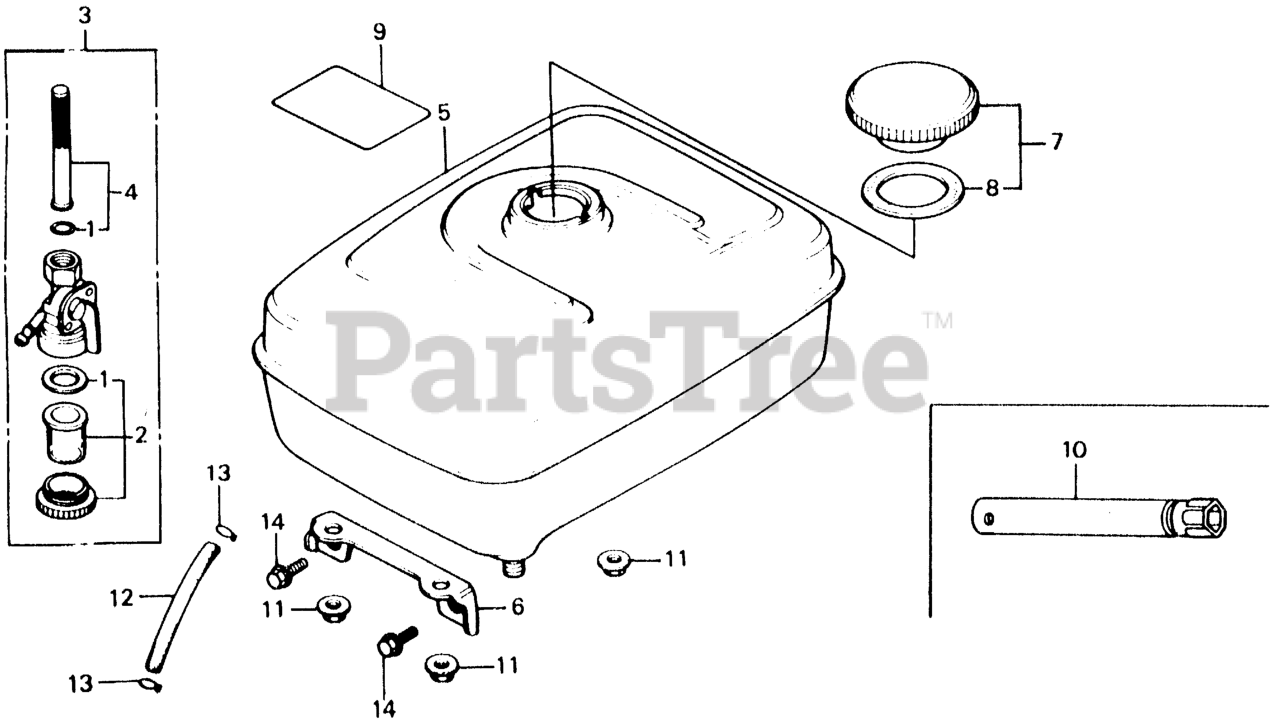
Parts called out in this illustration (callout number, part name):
1	GASKET SET, PETCOCK (CONTAINS 1 LARGE & 1 SMALL. USE AS NEEDED)
2	CUP, FUEL STRAINER
3	PETCOCK ASSY.
4	SCREEN SET
5	TANK, FUEL *NH31R* (MCKINLEY WHITE)
6	STAY, FUEL TANK
7	CAP, FUEL FILLER (BLACK) Use up to Engine SN 2115700.
7	CAP, FUEL FILLER (CHROME PLATED)
8	GASKET, FUEL FILLER CAP (39X58X3) (NOT AVAILABLE)
8	GASKET, FUEL FILLER CAP Use from Engine SN 1543258.
8	GASKET, FUEL FILLER CAP (39X58X3)
9	MARK, CAUTION (ENGLISH/FRENCH)(SPANISH)
10	WRENCH, SPARK PLUG (NOT AVAILABLE)
11	NUT, FLANGE (8MM)
12	BULK HOSE, FUEL (4.5X3000) (Honda Code 5137104). (4.5X140)
13	CLIP, TUBE (B8)
14	BOLT, FLANGE (8X16)
